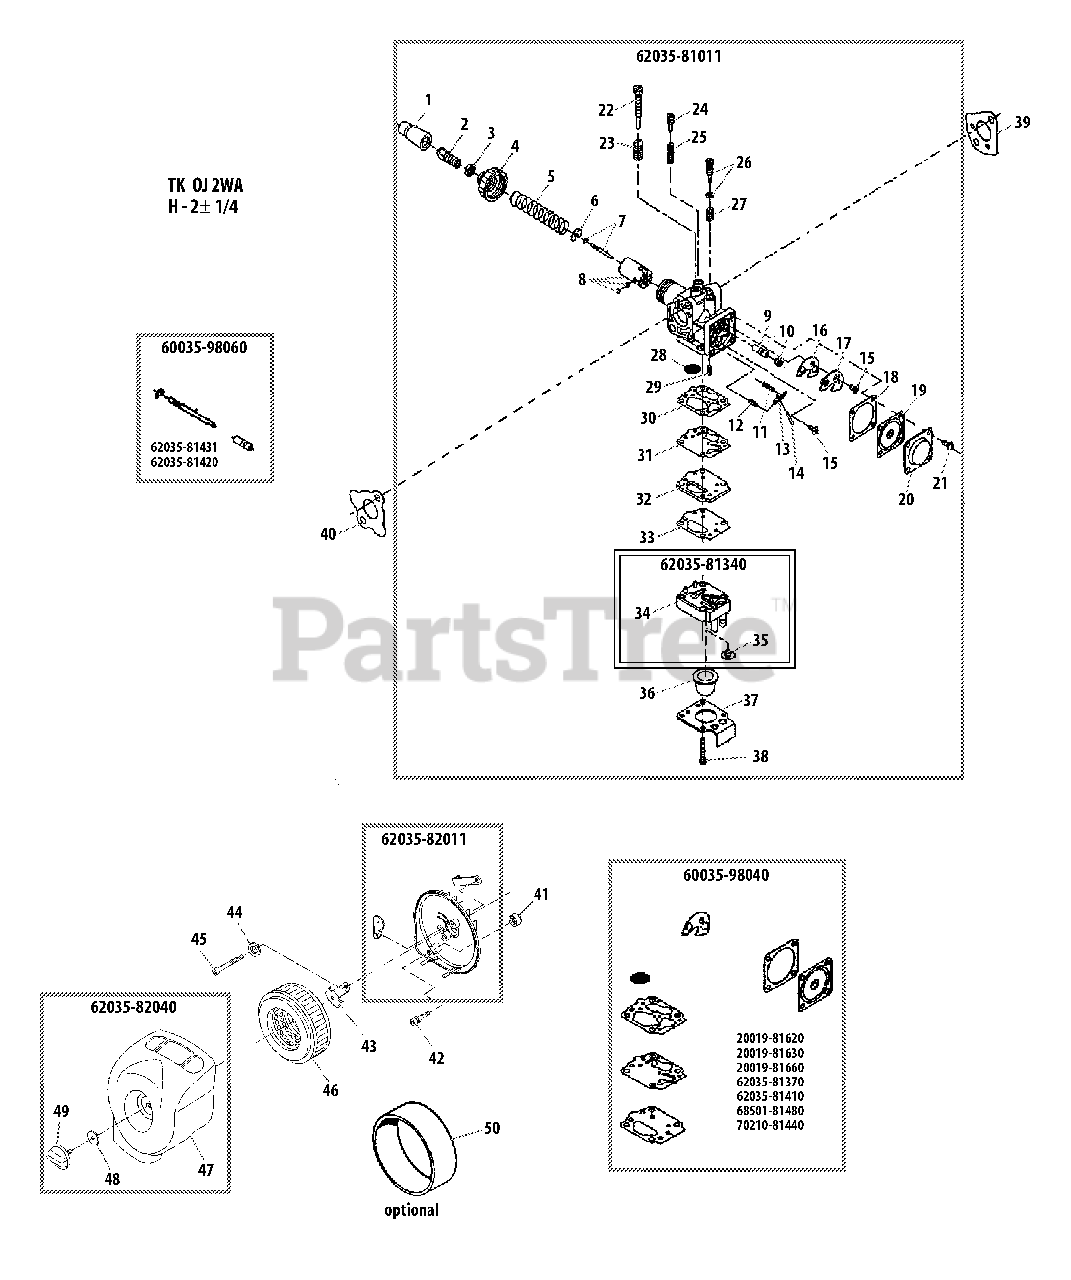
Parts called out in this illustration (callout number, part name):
1	GROMMET
2	NUT, CABLE ADJUST
3	LOCKNUT
4	CAP, CARBURETOR
5	SPRING
6	SPRING RECIEVE
7	NEEDLE, JET
8	SLIDE VALVE
9	NEEDLE, JET
10	HOLDER, JET
11	SPRING
12	VALVE, INLET NEEDLE
13	LEVER, METERING
14	PIN, METERING LEVER
15	SCREW, METERING LEVER PIN
16	GASKET
17	PLATE
18	GASKET
19	DIAPHRAGM, METERING
20	COVER, DIAPHRAGM
21	SCREW
22	SCREW, IDLE ADJUST
23	SPRING
24	SCREW, SLOW AIR
25	SPRING
26	SCREW, IDLE ADJUST
27	SCREW, IDLE ADJUST
28	SCREEN, SPARK ARRESTOR
29	SPRING
30	GASKET, PUMP
31	DIAPHRAGM, PUMP
32	PLATE, PUMP
33	GASKET, PUMP
34	COVER, PUMP
35	VALVE
36	BULB, PURGE
37	PLATE, PUMP
38	SCREW
39	GASKET
40	GASKET
41	INSULATOR
42	SCREW - 5X40
43	PLATE
44	LOCKWASHER - 5
45	SCREW - 5X75
46	FILTER, AIR
47	COVER, AIR FILTER
48	WASHER
49	THUMBSCREW
50	PRE-FILTER
60035-98040	DIAPHRAGM/GASKET KIT
60035-98060	NEEDLE/JET KIT
62035-81011	CARBURETOR
62035-81340	PUMP COVER ASSY
62035-82011	AIR FILTER CASE ASSY
62035-82040	AIR FILTER COVER ASSY
